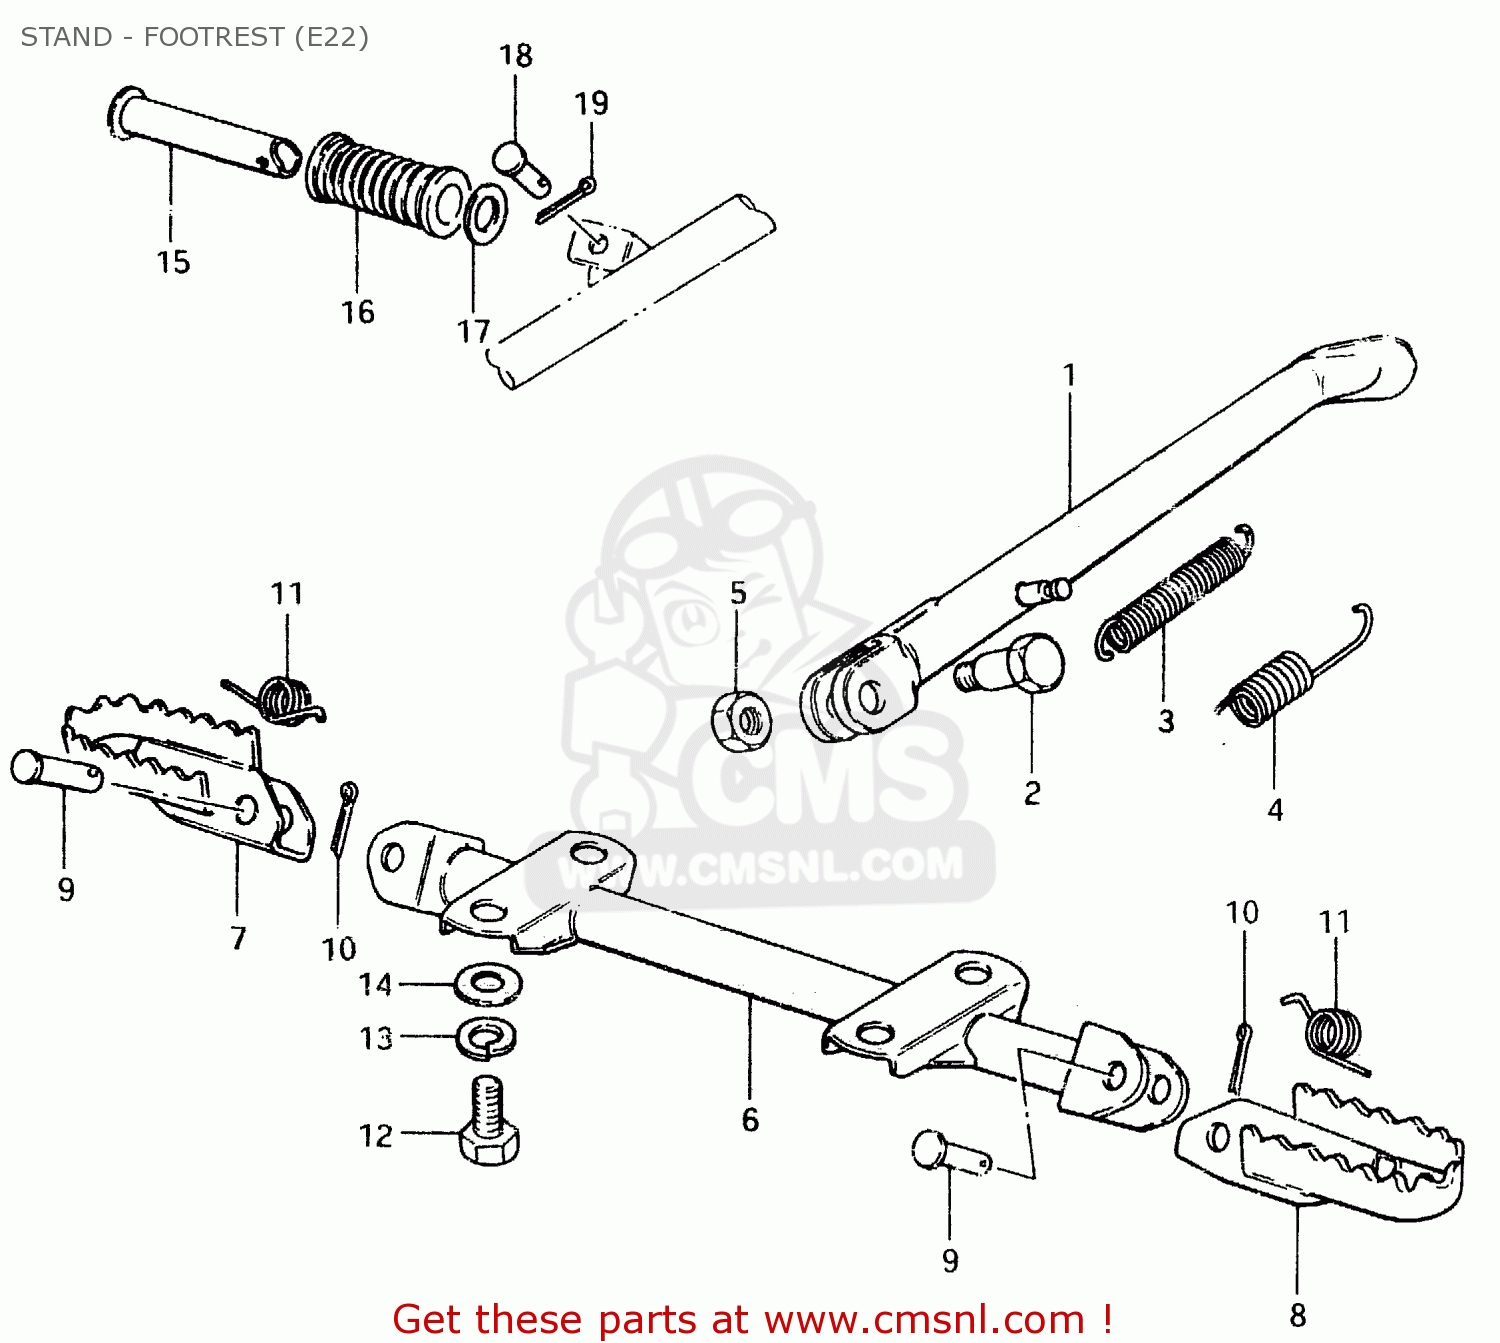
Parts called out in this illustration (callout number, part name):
1	STAND, PROP
2	BOLT
3	SPRING
4	SPRING, OUTER
5	NUT
6	BAR,FR FOOTREST
7	FOOTREST,FRONT
8	FOOTREST
9	PIN
10	PIN 20X20
11	SPRING
12	BOLT
13	LOCK WASHER
14	WASHER
15	BAR,FOOTREST RUBBER
16	RUBBER,PILLION FOOTREST
17	WASHER (19.5X32X2)
18	PIN
19	PIN 20X20
